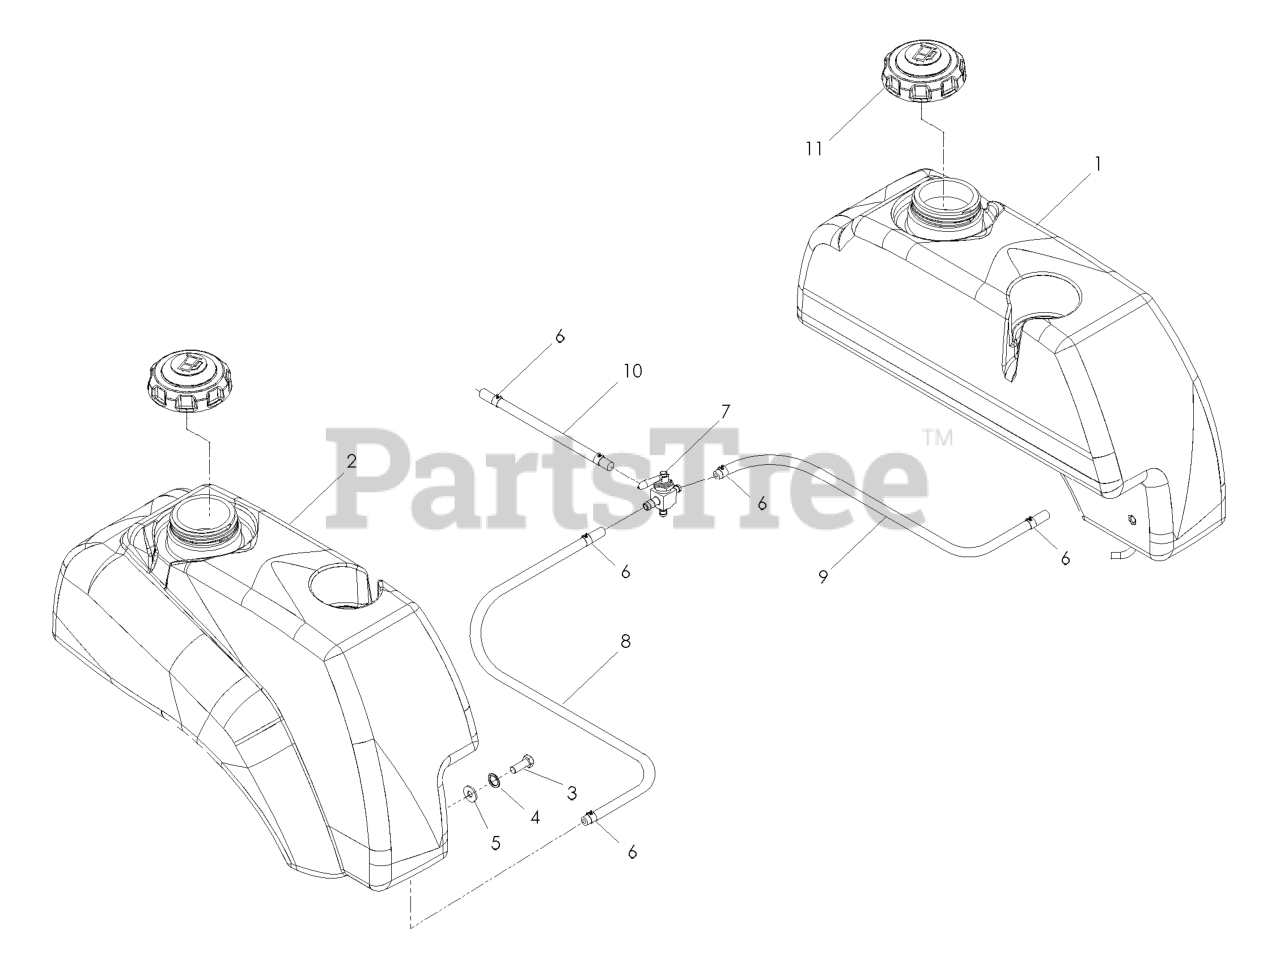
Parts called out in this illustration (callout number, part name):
1	LEFT TANK W/CUP HOLDER
2	FUEL TANK RT
3	HCS 5/16C X 3/4
4	WASHER.LOCK.HVY.HLCL.SPR.5/16
5	WASHER 5/16 FLAT
6	HOSE CLAMP
7	FUEL VALVE
8	FUEL LINE 24"
9	HOSE 1/4 X 28
10	FUEL LINE 13"
10	FUEL LINE 29.5"
11	FUEL CAP ANTI-SPLASH
